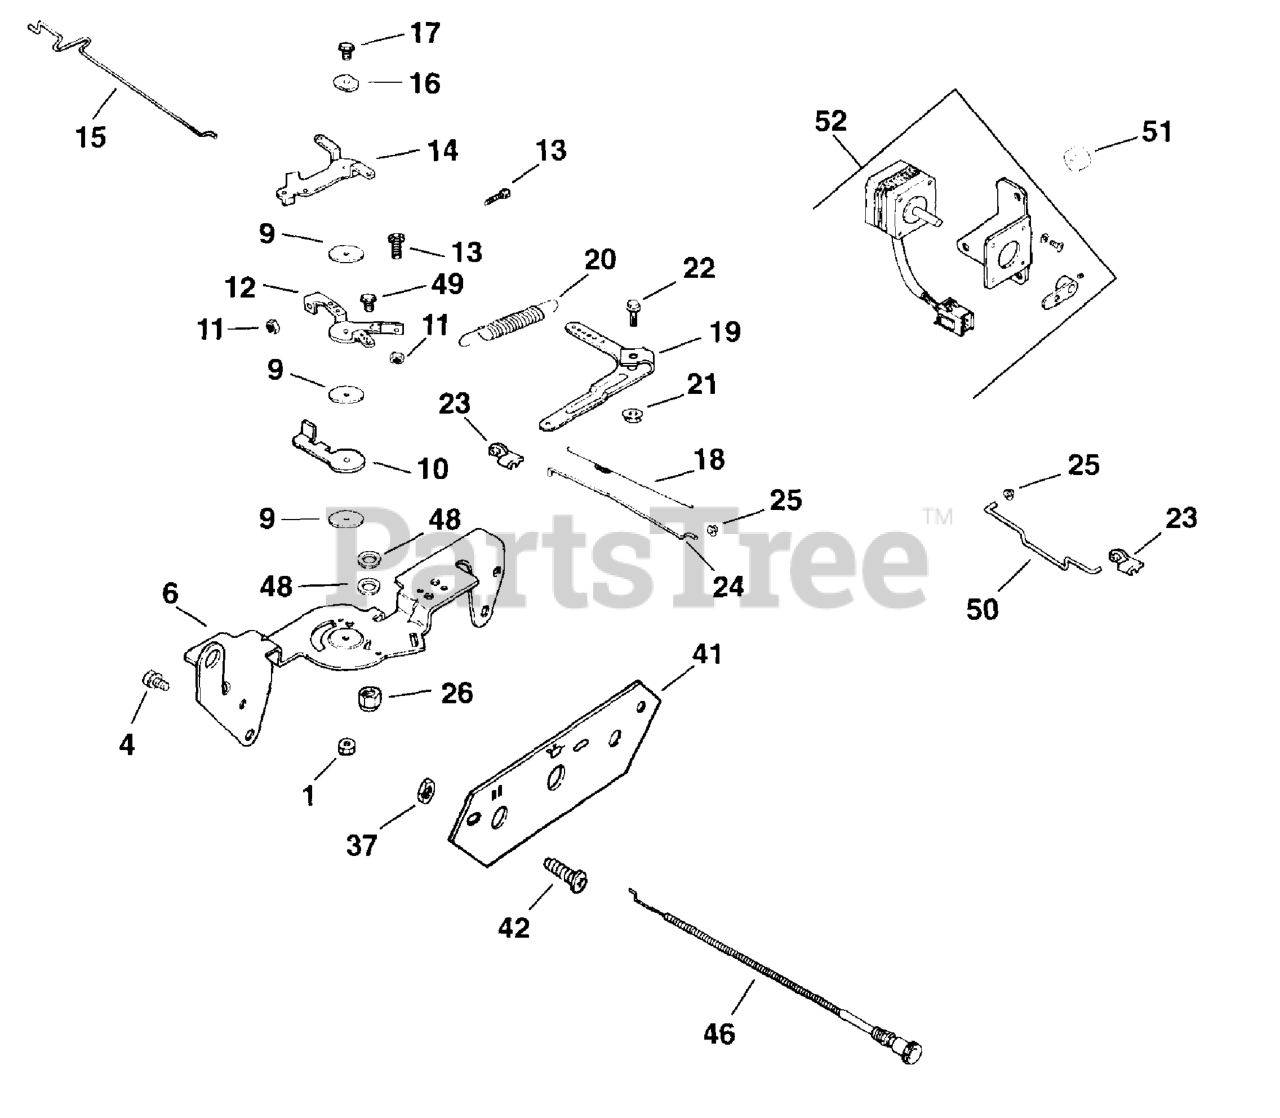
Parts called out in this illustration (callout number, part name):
1	Nut, hex. flange M5x0.8
4	SCREW - USE M-645016
6	BRACKET - USE 24 126 56
9	WASHER, FLAT 5.5 MM
10	LEVER,THROTTLE ACTUATOR-USE(24 090 65-S
11	Nut, hex. flange M4x0.7
12	LEVER, THROTTLE CONTROL
13	Screw, hex. cap M4x0.7x30
14	LEVER, CHOKE
16	WASHER, SPRING 1/4"
17	Screw, hex. flange M5x0.8x20
18	SPRING, LINKAGE
19	LEVER, GOVERNOR - DISCONTINUED
20	SPRING, GOVERNOR (PURPLE)
21	NUT - USE M-641060
22	Screw, hex. cap M6x1.0x25
23	BUSHING, THROTTLE LINKAGE
24	LINKAGE, THROTTLE
25	BUSHING, LINKAGE RETAINING
26	Nut, hex. M6x1.0
48	Washer, plain 9 mm
49	SCREW - USE M-650012
